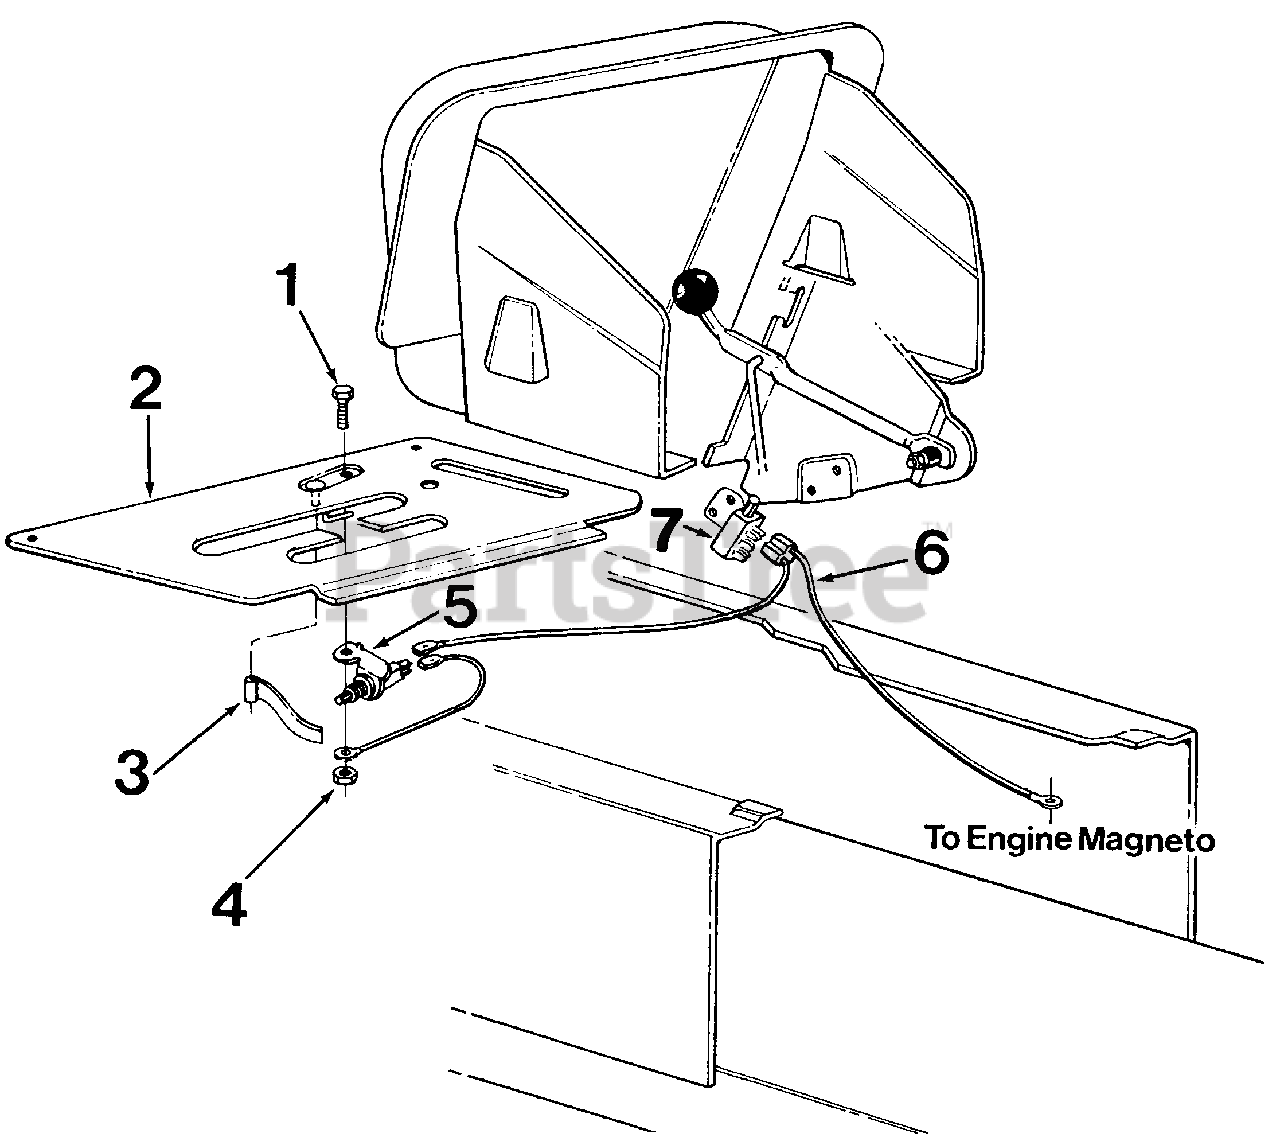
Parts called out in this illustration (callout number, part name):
1	Hex Bolt 1/4-20 x .50" Lg.
2	Transmission Cover Ass'y.
3	Switch Actuator Spring Lever
4	Hex Nut 1/4-2 Thd.
5	Safety Switch
6	Reverse Lockout Wire Harness
7	Safety Switch
